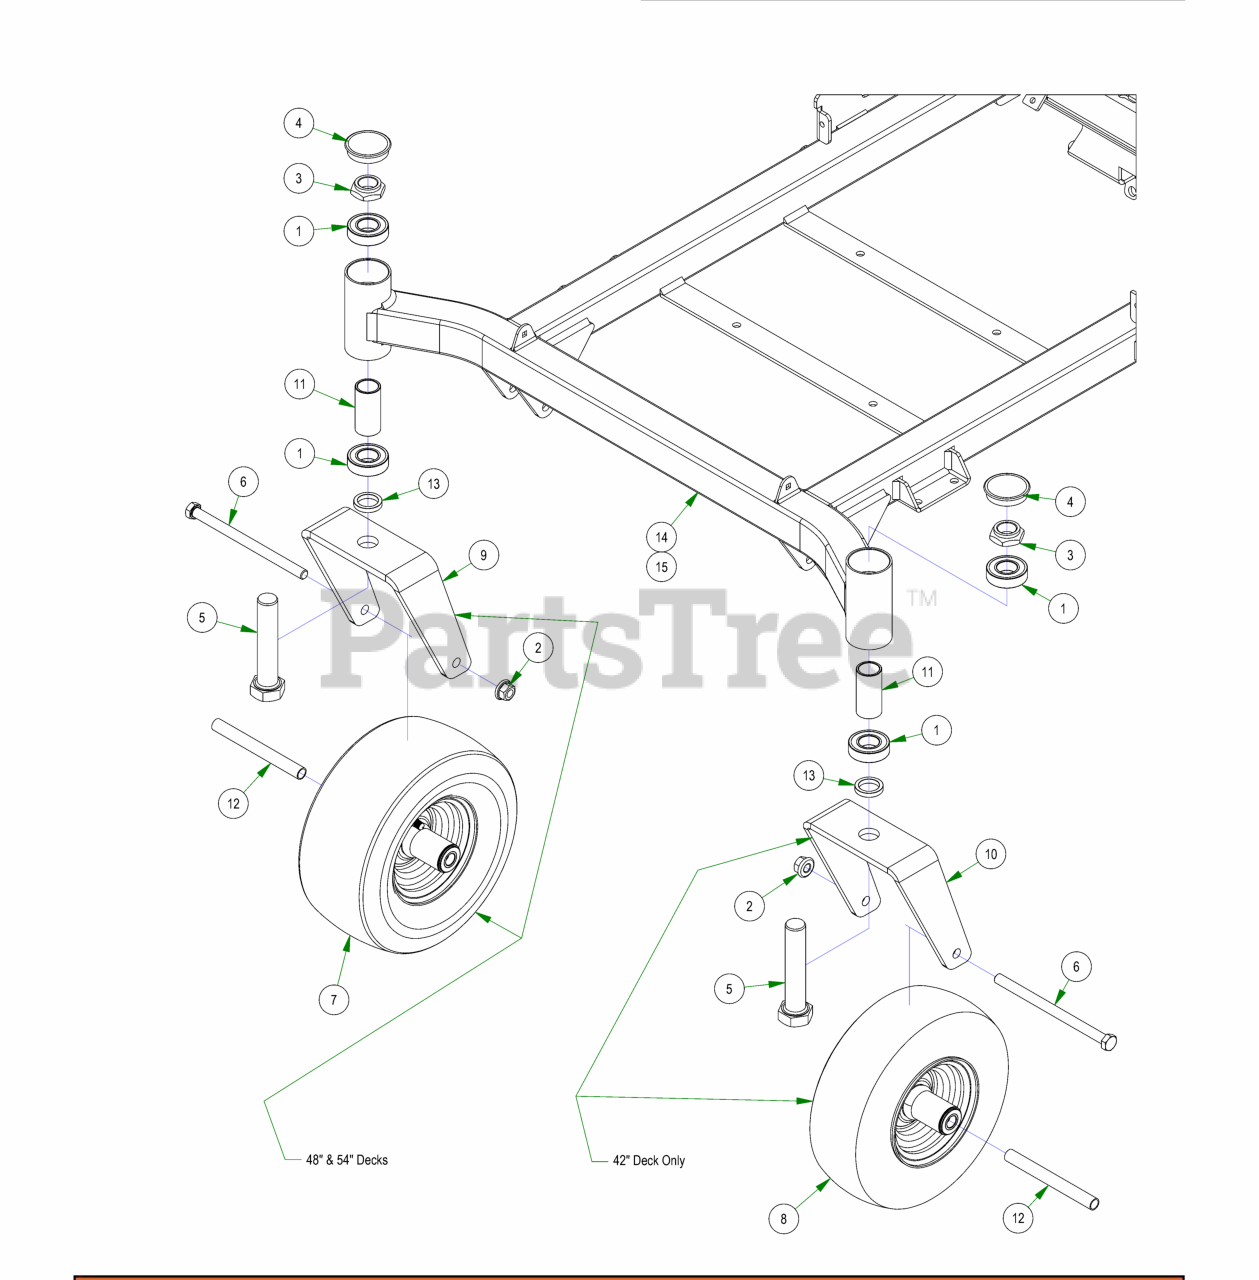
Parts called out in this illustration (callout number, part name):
1	1641 BEARING W/2 CONTACT RUBBER SEALS
2	1/2-13 NYLON INSERT FLANGE LOCKNUT ZINC
3	1"-14 NYLON INSERT JAM LOCKNUT ZINC
4	2017 Bearing Cover
5	1"-14 X 5 HEX CAP SCREW (GR.8) ZINC YELLOW
6	1/2-13 X 7-1/2 HEX CAP SCREW (GR.5) ZINC
7	11x6.00-5 Front Assembly - Black Wheel
8	11 x 4.00 - 5 Front Tire Assembly (Black)
9	2017 MZ Front fork
10	MZ Front Fork (42" ONLY)
11	2016 Front Bearing Spacer
12	Front Wheel Spanner
13	1.02 ID X 1.38 OD X .250 THK SPACER ZINC
14	2024 MZ 42-48 Frame
15	2024 MZ-Avenger 54-60 Frame
